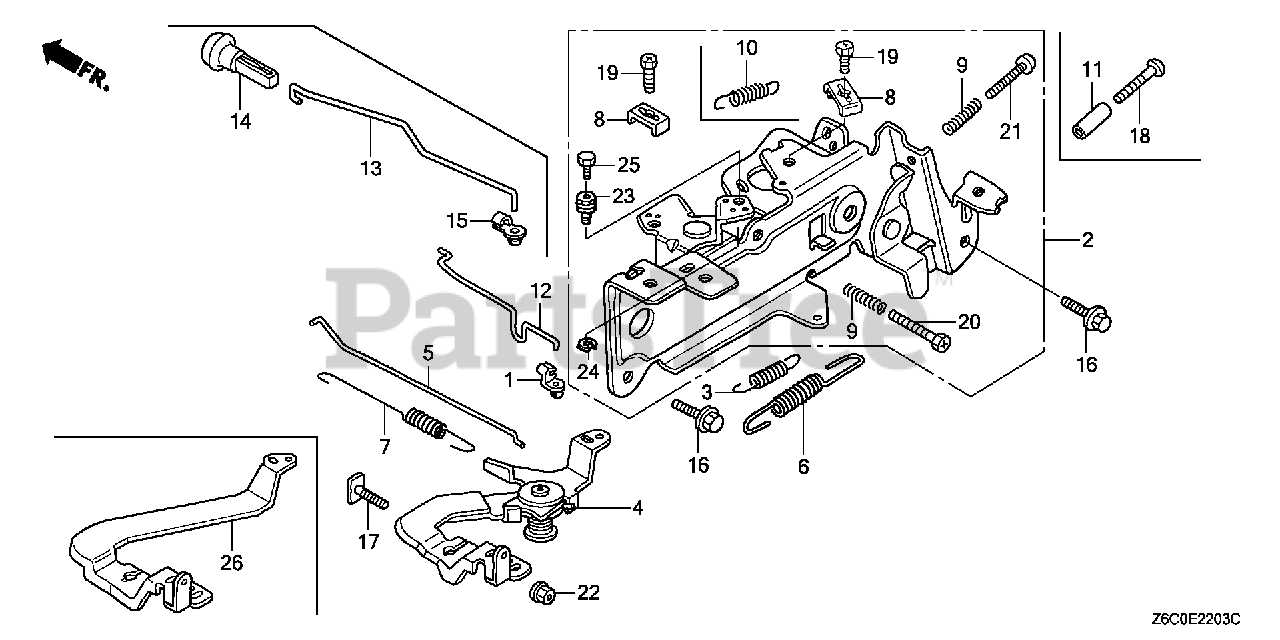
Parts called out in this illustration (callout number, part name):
1	JOINT, ROD
2	CONTROL ASSY. (AUTO THROTTLE)
3	SPRING, STARTER
4	ARM, GOVERNOR
5	ROD, GOVERNOR
6	SPRING, GOVERNOR (MANUAL)
7	SPRING, THROTTLE RETURN
9	SPRING, CONTROL ADJUSTING Use from Engine SN 2327377.
12	ROD, CHOKE CONTROL
13	ROD, CHOKE KNOB
14	KNOB, CHOKE
15	BUSH, LINKAGE
16	BOLT, FLANGE (6X14)
17	BOLT, GOVERNOR ARM
20	BOLT, SLOT (5X25)
21	SCREW, PAN (5X35)
22	NUT, FLANGE (6MM)
